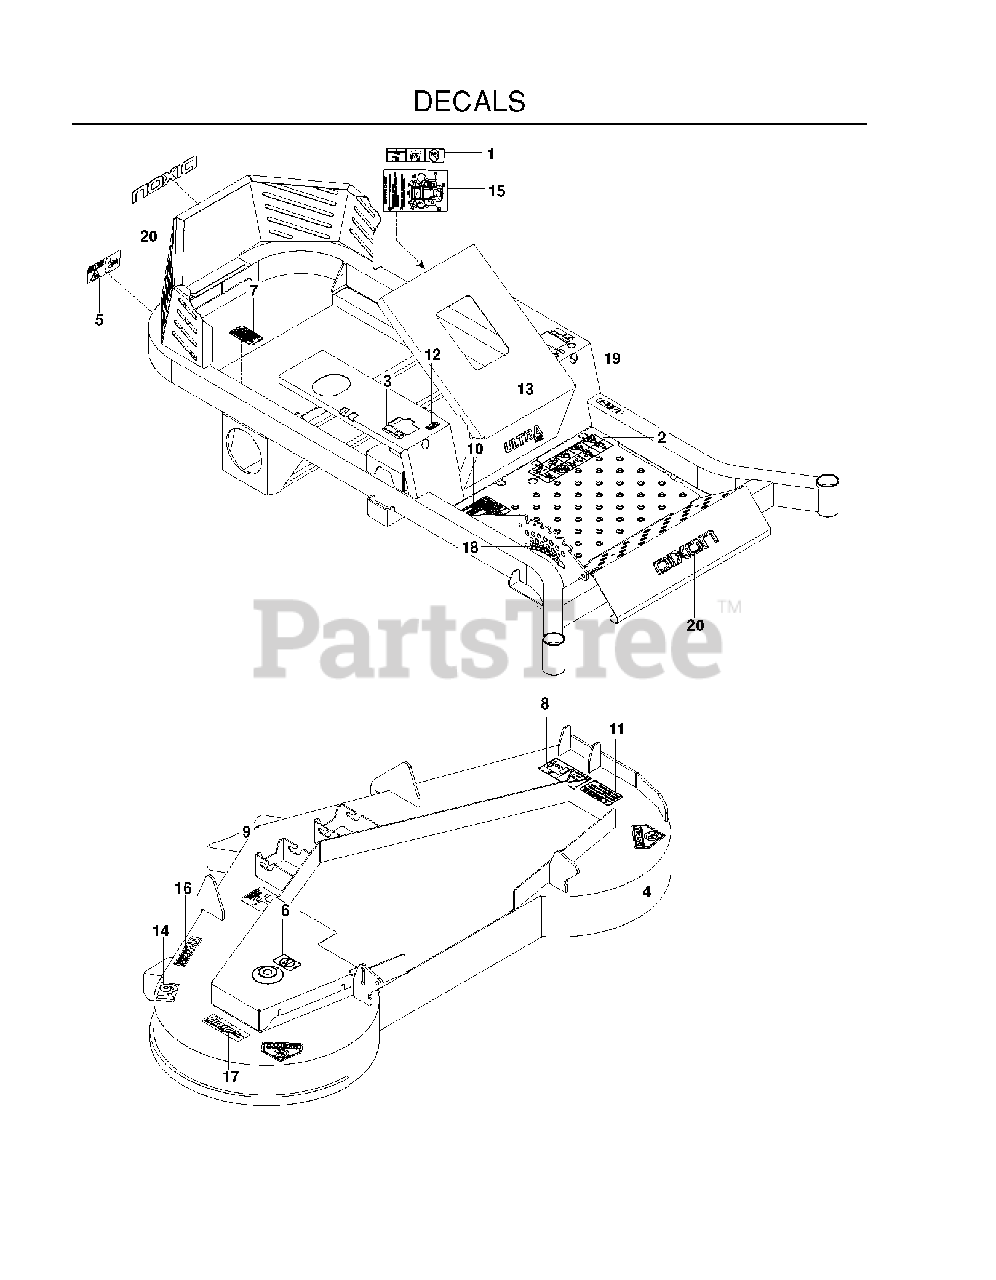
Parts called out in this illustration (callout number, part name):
1	DECAL, BATTERY
2	DECAL, WARNING
3	DECAL, MOTION CONTROL
4	DECAL, CPSC
5	DECAL, BELT DRIVE
6	DECAL, NO STEP
7	DECAL, PROP. 65
8	DECAL, EURO SEVERING
9	DECAL, BELT ROUTING
10	DECAL, WARNING
11	DECAL, CAUTION
12	DECAL, TRACKING
14	DECAL, 61
15	DECAL, SERVICE
16	DECAL, TRI-FORCE
17	DECAL, FUSION
18	DECAL, HEIGHT ADJUSTMENT
19	DECAL, PARK BRAKE
